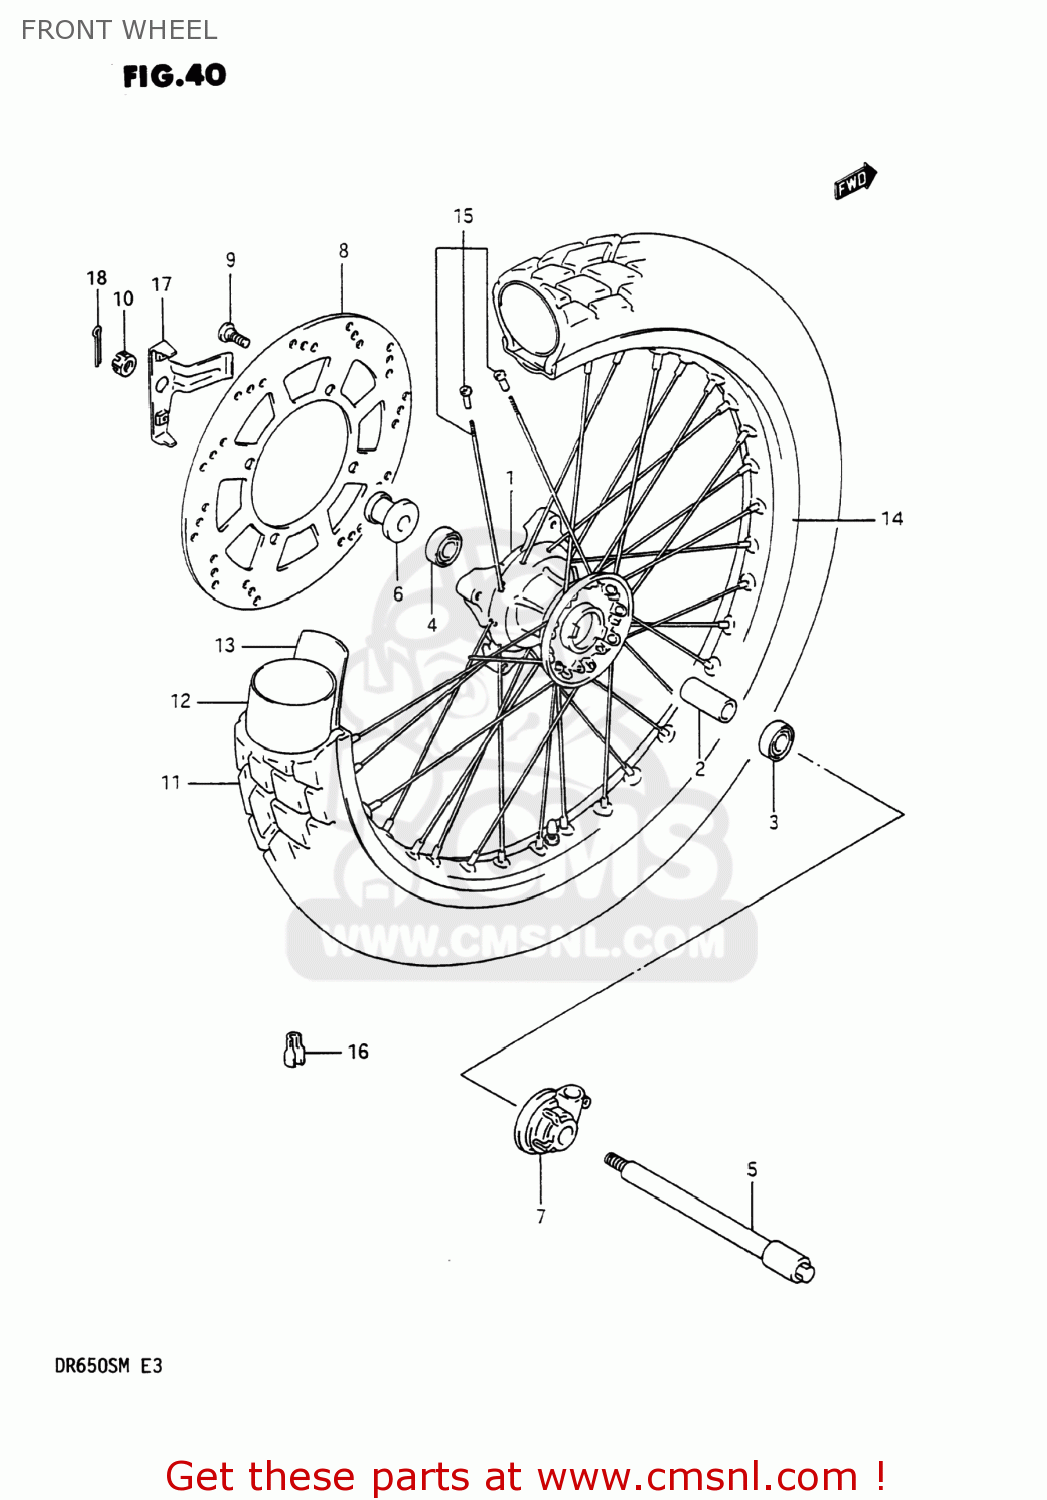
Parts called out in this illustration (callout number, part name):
1	HUB,FRONT WHEEL
2	SPACER,FR HUB BEARING
3	BEARING(15X32X15.9)
4	BEARING
5	AXLE,FRONT
6	SPACER,FRONT AXLE,LEFT
7	BOX ASSY,SPEEDOMETER GEAR
8	DISC,FR BRAKE
9	BOLT,BRAKE DISC
10	NUT 12MM
11	TIRE,FRONT
12	TUBE,INNER
13	PROTECTOR,WHEEL,INNER
14	RIM,FR WHEEL(21X1.85)
15	SPOKE SET,FR WHEEL
16	BALANCER,WHEEL
17	PLATE,PROTECTOR SET
18	COTTER PIN
